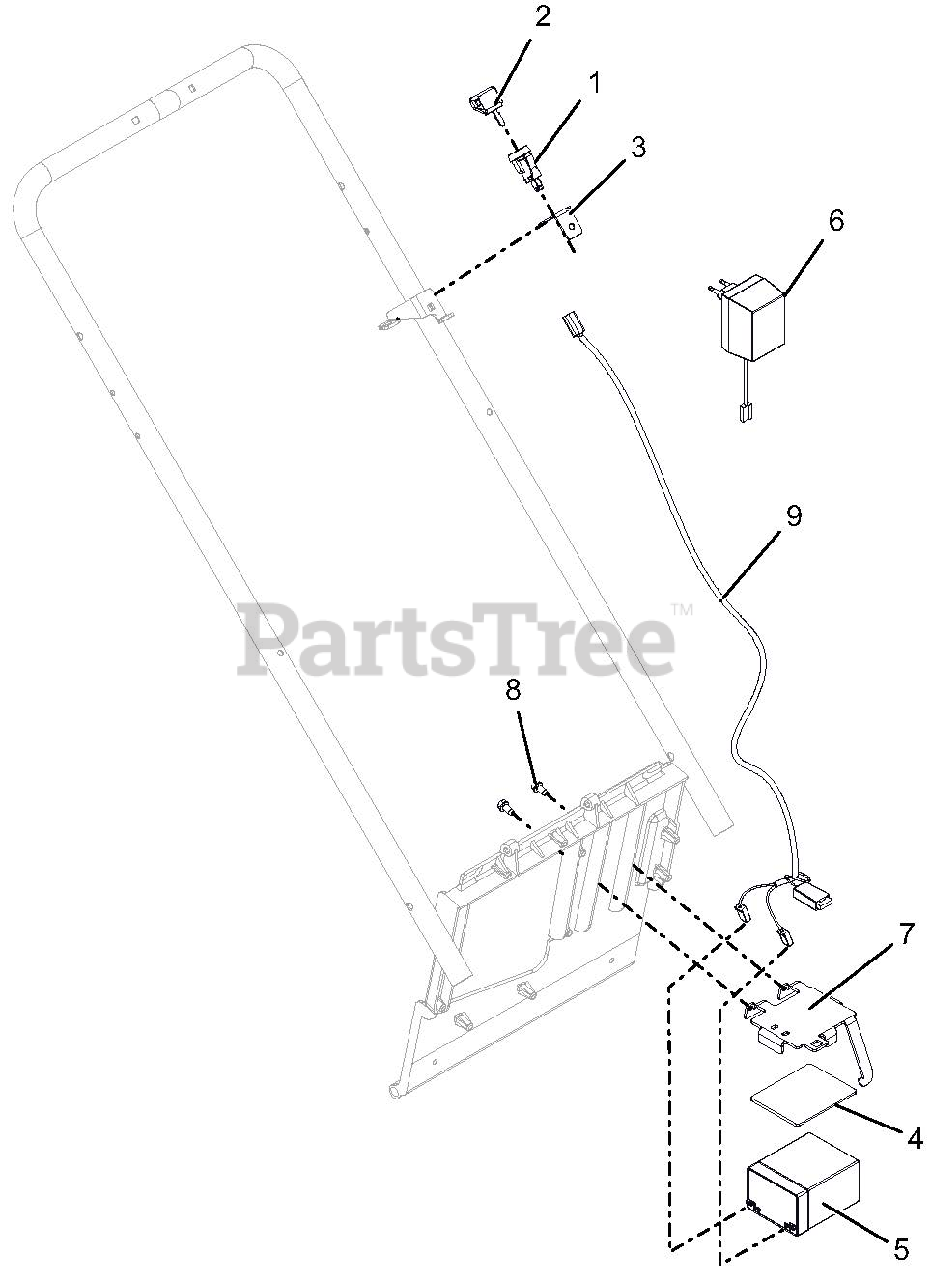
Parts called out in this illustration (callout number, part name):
1	SWITCH, KEY
2	KEYS, IGNITION
3	BRKT, KEY SWITCH
4	PAD, BATTERY, LM
5	BATTERY, AGM, 2.9AH, GNRL PRPS
6	CHARGER, BATTERY - CE
7	BRKT, BATTERY HOLD DOWN
8	SCR-TAP .25-20X.50 HWH TR YWZ
9	HARNESS, ELEC START
